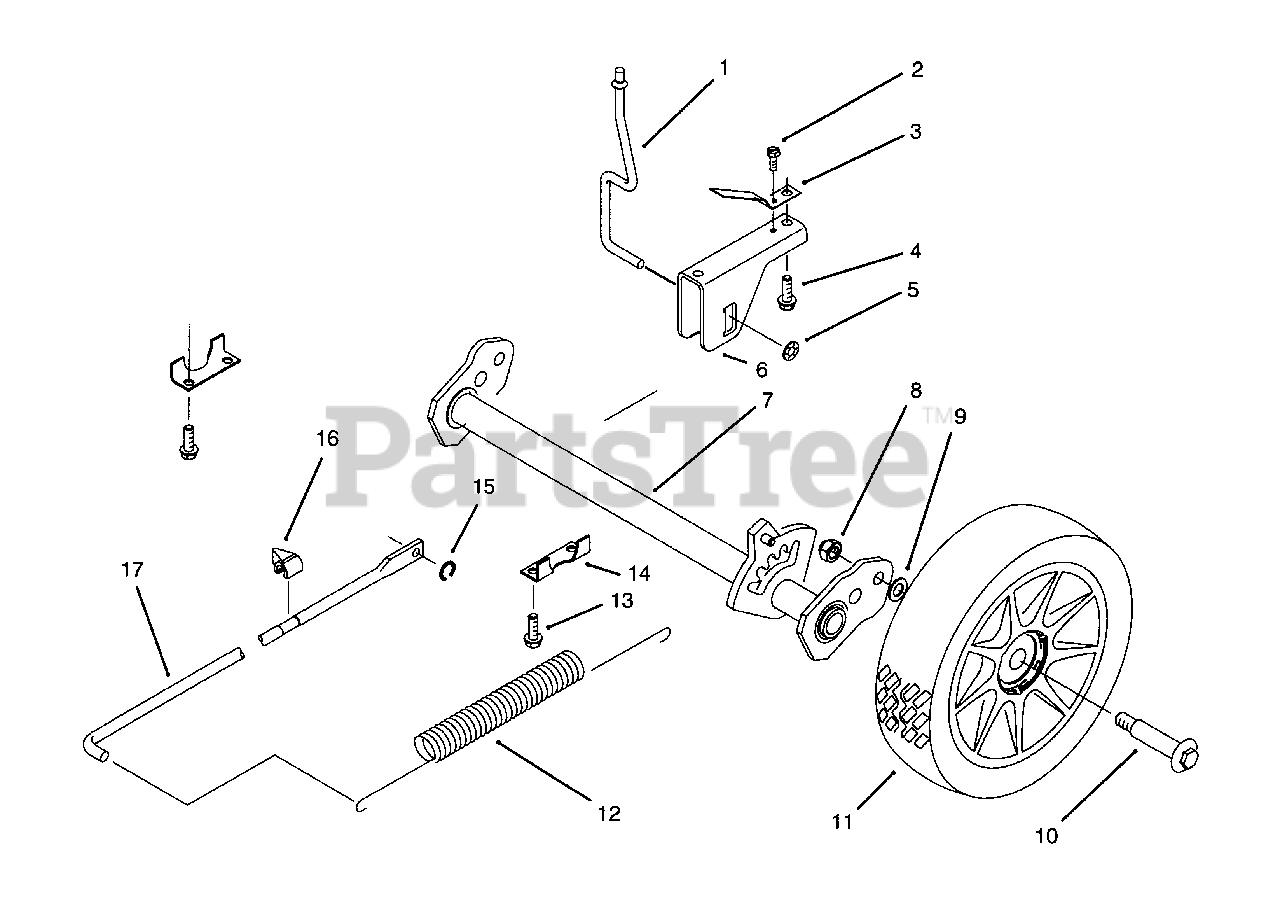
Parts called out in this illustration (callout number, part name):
1	Rod-Trigger
2	Screw-Tapping
3	Spring-Trigger Retainer
6	Saddle-H.O.C.
7	Arm-Pivot
8	Nut-Lock
10	Bolt-Shoulder
11	Wheel & Tire Assembly
12	Spring-Counterbalance
13	Screw-Tapping
14	Plate-Securing Rear
15	Ring-Grip
16	Indicator-H.O.C.
17	Rod-Link
